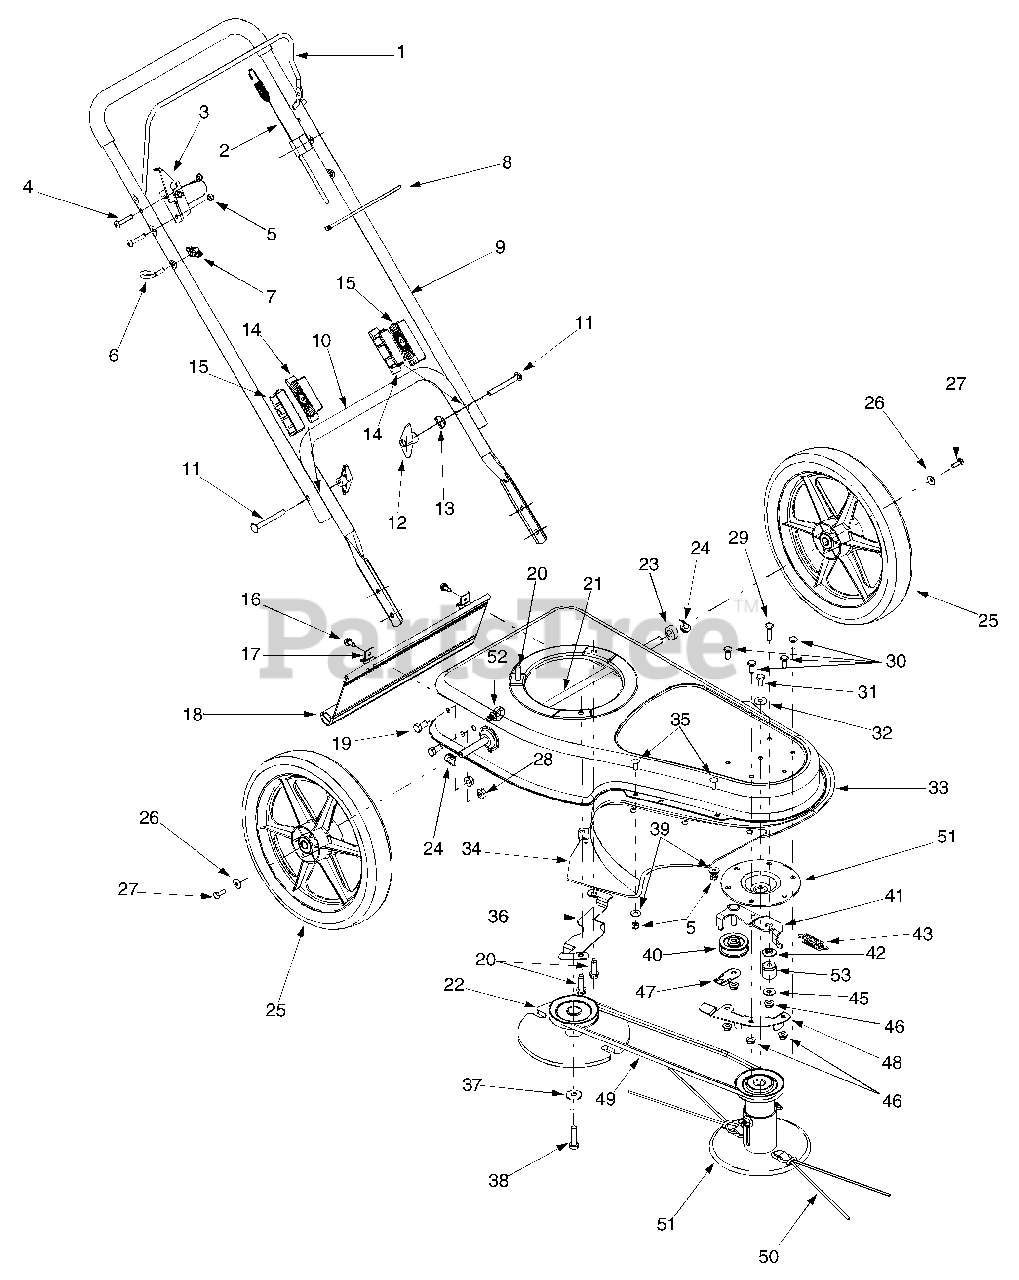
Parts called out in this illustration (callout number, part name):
2	Engagement Cable
3	Control Lock Bracket
4	Machine Screw 1/4-20 x 1.50
5	Hex Lock Nut 1/4-20
6	Eye Bolt 1/4-20
8	Cable Tie
13	Shoulder Washer .320 ID x .93 OD
14	Lower Handle Connector
15	Upper Handle Connector
16	Hex Washer Screw 1/4-14 x .625
17	Trail Shield Clip
18	Trail Shield
19	Hex Cap Screw 3/8-16 x .750
20	Hex Washer Screw 3/8-16 x 1.25
21	Trimmer Axle
22	Flywheel Pulley
23	Spacer .51 ID x 1.0 OD
24	Spacer Washer .501 ID x 1.0 OD
25	Wheel Assembly
26	Bell Washer .265 ID x .75 OD
27	Hex Cap Screw 1/4-20 x .75
28	Flange Lock Nut 3/8-16
29	Screw 5/16-18 x 1.25
30	Screw 5/16-18 x .75
31	Hex Cap Screw 5/16-24 x .625
32	Bell Washer .325 ID x .930 OD
35	Hex Carriage Screw 1/4-20 x .75
38	Hex Cap Screw 3/8-24 x 1.50
39	Flat Washer .28 ID x .74 OD
40	Idler Pulley
41	Idler Bracket Assembly
42	Idler Spacer
43	Extension Spring .50 Dia x 1.88 Lg
44	Handle Grip
45	Flat Washer
46	Flange Lock Nut 5/16-18
49	V-Belt
50	Trimmer Line .155 Dia
51	Spindle Assembly
52	Cable Retainer Clip
